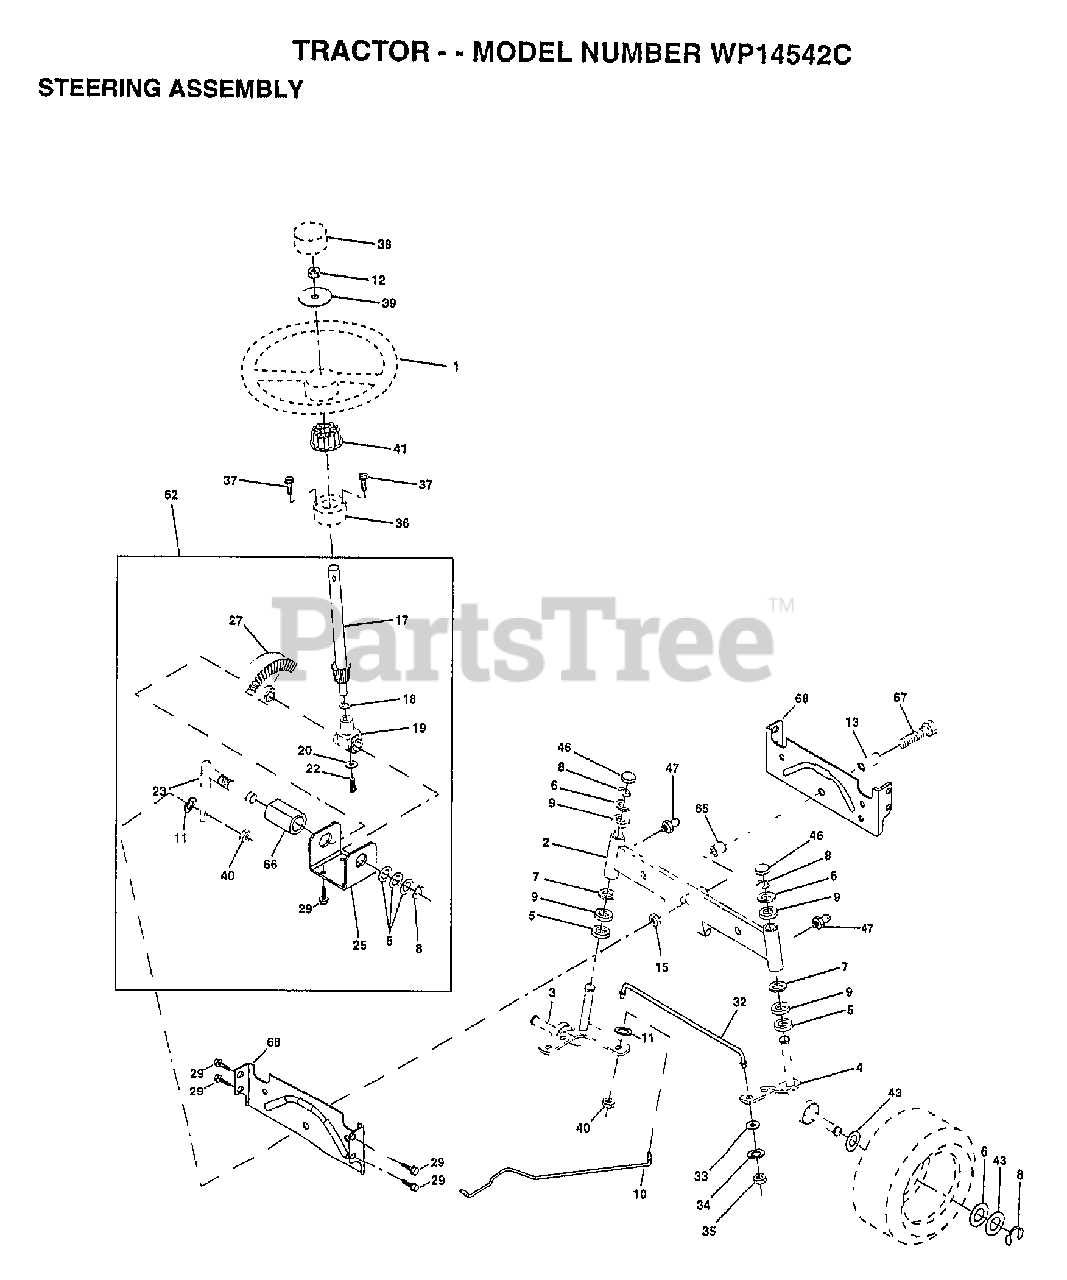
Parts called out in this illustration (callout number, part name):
2	AXLE ASM
3	SPINDLE.ASM.LH
4	"SPINDLE ASM,RH"
5	WASHER .T
6	WASHER
7	WASHER
8	RING
9	COL. SRTG. BEAR.
10	DRAGLINK-STAMPED
11	LOCKWASHER
13	BEARING AXLE
15	"NUT-LOC,FLANGE LT"
17	SHAFT ASM STEERNG
18	THRUST WASHER
19	SUPPORT.SHAFT
22	SCREW HEX SOC1/4-
25	BRKT-STEERING
27	GEAR SECTOR
29	SCREW
32	ROD.TIE.19.75
33	WASHER M
34	LOCKWASHER
35	NUT.LOCK.5/16-24
36	BUSHING.STRG.3/4
37	"SCREW-TT,10-32 FL"
38	"INSERT,STR WHEEL"
39	WASHER
40	GRIPCO NUT
41	ADAPTER LT
43	WASHER
46	CAP
47	ZERK M
62	KIT STEERING ASM
65	SPACER AXLE
66	"BEARING-ARM,PITMA"
67	BOLT
68	BRACE AXLE
